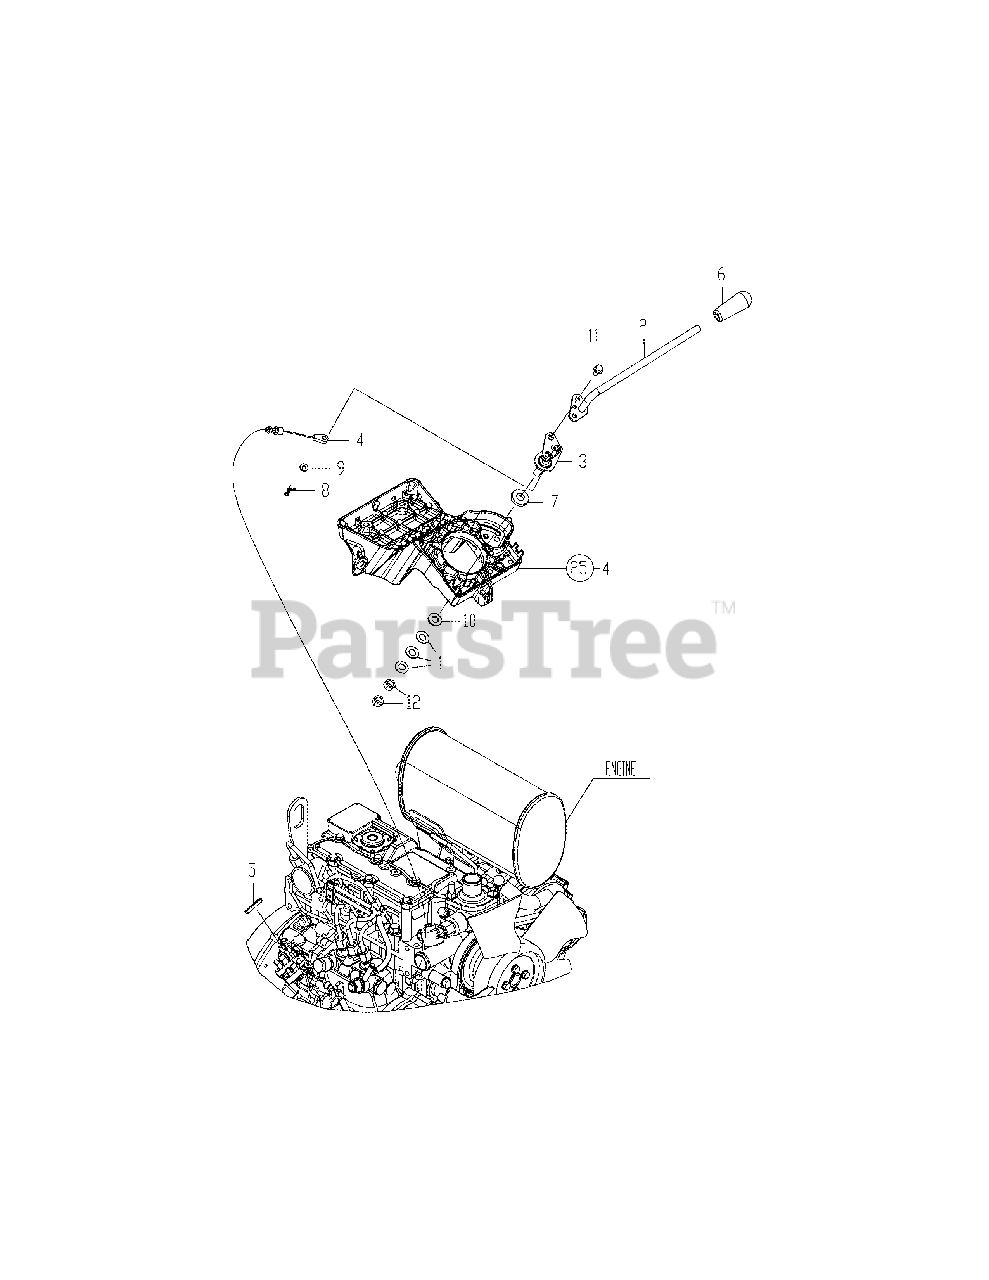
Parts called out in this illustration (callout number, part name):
1	Washer, Conical 10
2	Control Lever, Head
3	Control Lever, Base
4	Cable Assy, Control
6	Knob, Accel. Lever
7	Spacer, 13X26X5
